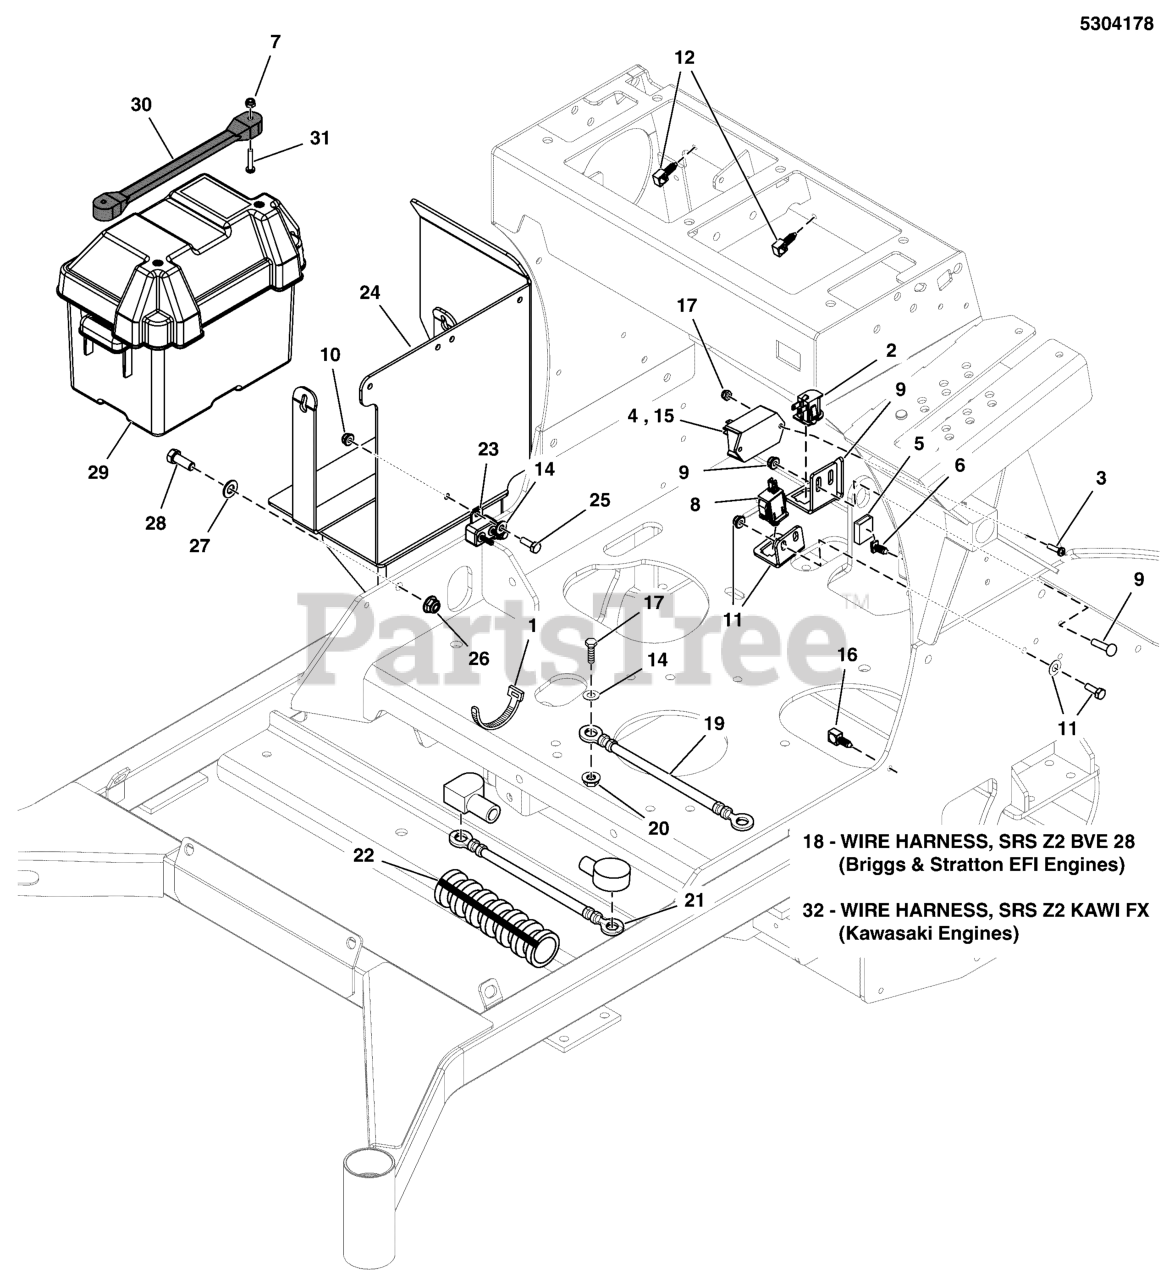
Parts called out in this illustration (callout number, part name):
1	TIE, SELF-LOCKING, 12"
2	SWITCH, SEAT
3	SCREW, #10-24 X 3/4 ROUND PHILLIPS
4	MODULE, TIME DELAY
5	PART OF WIRE HARNESS
6	FIR TREE MOUNT, PACKARD
7	NUT, #10-24 HEX NYLON LOCK
8	SWITCH, PLUNGER, NO, SINGLE POLE SNAP-IN
9	SEE OPERATOR COMPARTMENT GROUP
10	NUT, 1/4-20 HEX NYLOCK FLANGE
11	SEE PARKING BRAKE GROUP
12	ROSEBUD LOOM CLIP
13	BATTERY, WET ( BCIU1, 350 CCA)
14	WASHER, 1/4 SAE
15	MODULE, TIME DELAY, NO DIODE
16	ROSEBUD CLIP, 3/8"
17	HHCS, 1/4-20 X 0.625, GR5, ZINC/CLEAR
18	WIRE HARNESS, SRS Z2, BVE 28-NO NEUTRAL
19	BATTERY CABLE, NEG, 22, 1/4-5/16
20	NUT, 1/4-20 HEX SERR. FLANGE
21	BATTERY CABLE, POS, 22, 1/4-5/16
22	WIRE LOOM, 3/8 ID X 19 IN
23	BREAKER-CIRCUIT 12VOLT 20AMPS W/TAB
24	WELD, BATTERY BOX, STAND ON - RED
25	BOLT, 1/4-20 X 3/4 GD5 CZ
26	NUT, 3/8-16 HEX NYLOCK FLANGE
27	WASHER, 3/8 SAE
28	BOLT, 3/8-16 X 1" GD5 CZ
29	BATTERY BOX, W/ DRAIN HOLE
30	STRAP, RUBBER
31	SCREW, #10-24 X 1 RS, CZ
32	WIRE HARNESS, SRS Z2, KAWI FX
